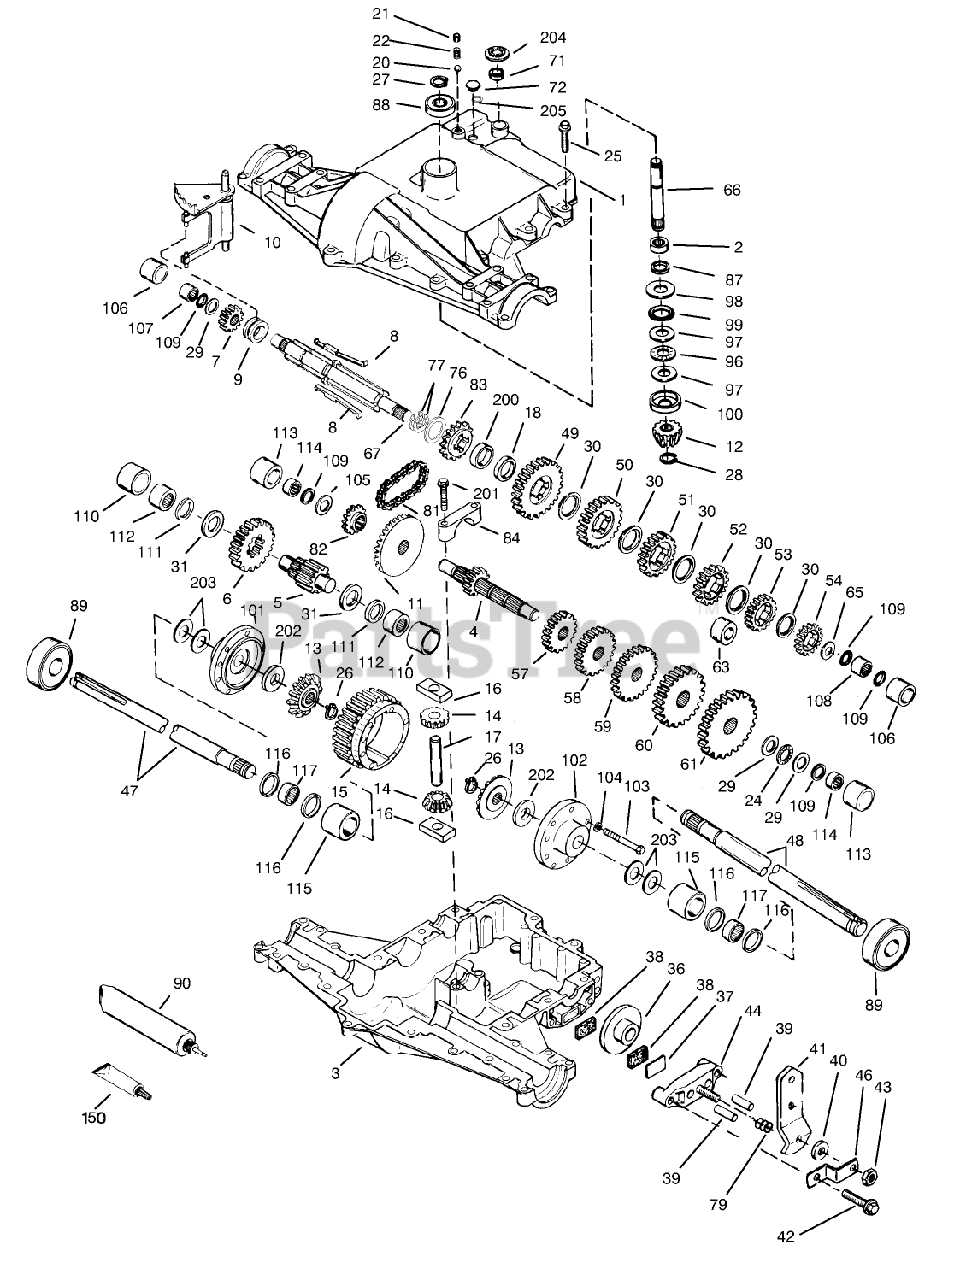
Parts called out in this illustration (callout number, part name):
1	Cover-Transaxle (Only On: 72042, 72062)
2	Bearing-Needle (Only On: 72042, 72062)
3	Case-Transaxle (Only On: 72042,72062)
4	Countershaft-Gear 9t (Only On: 72042, 72062)
5	Shaft-Output (Only On: 72042, 72062)
6	Gear-Output 35t (Only On: 72042,72062)
7	Gear-Spur 15t (Only On: 72042,72062)
8	Key-Shift (Only On: 72042, 72062)
8	Key-Shift (820-024A Only)
9	Collar-Shift
9	Shift Collar
10	Fork-Shift (Only On: 72042,72062)
10	Fork-Shift (820-024A Only)
11	Gear-Bevel 33t (Only On: 72042, 72062)
12	Pinion-Input Bevel 13t (Only On: 72042, 72062)
13	Gear-Bevel
14	Pinion-Bevel
15	Gear-Ring (Only On: 72042,72062)
16	Biock-Drive
17	Pin-Drive
18	Spacer .350-.340 Thick (Only On: 72042, 72062)
20	Ball-Steel
21	Screw-Set
22	Spring
24	Bearing-Thrust
25	Screw 5/16-18x1 1/4
26	Ring-Snap
27	Ring-Snap
28	Ring-Retainer
29	Washer
30	Washer
31	Washer (Only On: 72042,72062)
36	Washer (Only On: 72042, 72062)
37	Brake Pad Plate
38	Pad-Brake 2/Pkg
39	Dowel Pin
40	Washer
41	Lever-Brake
42	Ring Set (.020 O S)
43	Locknut
44	Nozzle-Carburetor
46	Bracket
47	Axle 12 9/16" Long (Only On: 72042,72062)
48	Axle 16 7/16" Long (Only On: 72042, 72062)
49	Gear-Spur 41t (Only On: 72042,72062)
50	Gear-Spur 35t (Only On: 72042,72062)
51	Gear-Spur 30t (Only On: 72042, 72062)
52	Gear Spur 25t (Only On: 72042,72062)
53	Gear Spur 22t (Only On: 72042,72062)
54	Gear Spur 19t
57	Gear Spur 15t (Only On: 72042, 72062)
58	Gear Spur 20t (Only On: 72042, 72062)
59	Gear Spur 25t (Only On: 72042, 72062)
60	Gear Spur 28t (Only On: 72042,72062)
61	Gear Spur 30t (Only On: 72042,72062)
65	Washer
66	Shaft-Input 30.910" Lg (Only On: 72042, 72062)
67	Shaft-Shifter/Brake (Only On: 72042, 72062)
67	Shaft-Shifter/Brake (820-024A Only)
71	Cut Seal-Square
72	Plug-Threaded 5/16-18
76	Washer
77	Inverted Retaining Ring
79	Piston ASM (.020 O S)
81	Chain-Roller
82	Sprocket 10t
83	Sprocket (14 teeth)
84	Cap-Bearing (Only On: 72042, 72062)
87	Seal Oil
88	Bearing-Ball
89	Bearing-Ball
90	Grease 32 Oz
96	Bearing-Thrust (Only On: 72042,72062)
97	Washer
98	Washer (Only On: 72042, 72062)
99	O Ring (Only On: 72042,72062)
100	Washer-Cupped (Only On: 72042,72062)
101	Carrier-Differential (Only On: 72042, 72062)
102	Carrier-Differential (Only On: 72042, 72062)
103	Screw-Hex Hd.
104	Lockwasher
105	Washer (Only On: 72042,72062)
106	Sleeve (Only On: 72042,72062)
107	Bearing-Needle (Only On: 72042,72062)
108	Bearing-Needle (Only On: 72042, 72062)
109	O Ring
110	Sleeve (Only On: 72042, 72062)
111	Ring-Square Cut (Only On: 72042, 72062)
112	Bearing-Needle (Only On: 72042, 72062)
113	Sleeve (Only On: 72042, 72062)
114	Bearing-Needle (Only On: 72042,72062)
115	Sleeve (Only On: 72042,72062)
116	Ring-Square Cut (Only On: 72042,72062)
117	Bearing-Needle (Only On: 72042,72062)
150	Gasket Eliminator
200	Spacer .276-.268 Thick (Only On: 72042, 72062)
201	Ring Set (.020 O S)
202	Washer
203	Washer
204	Pushnut
205	O Ring
